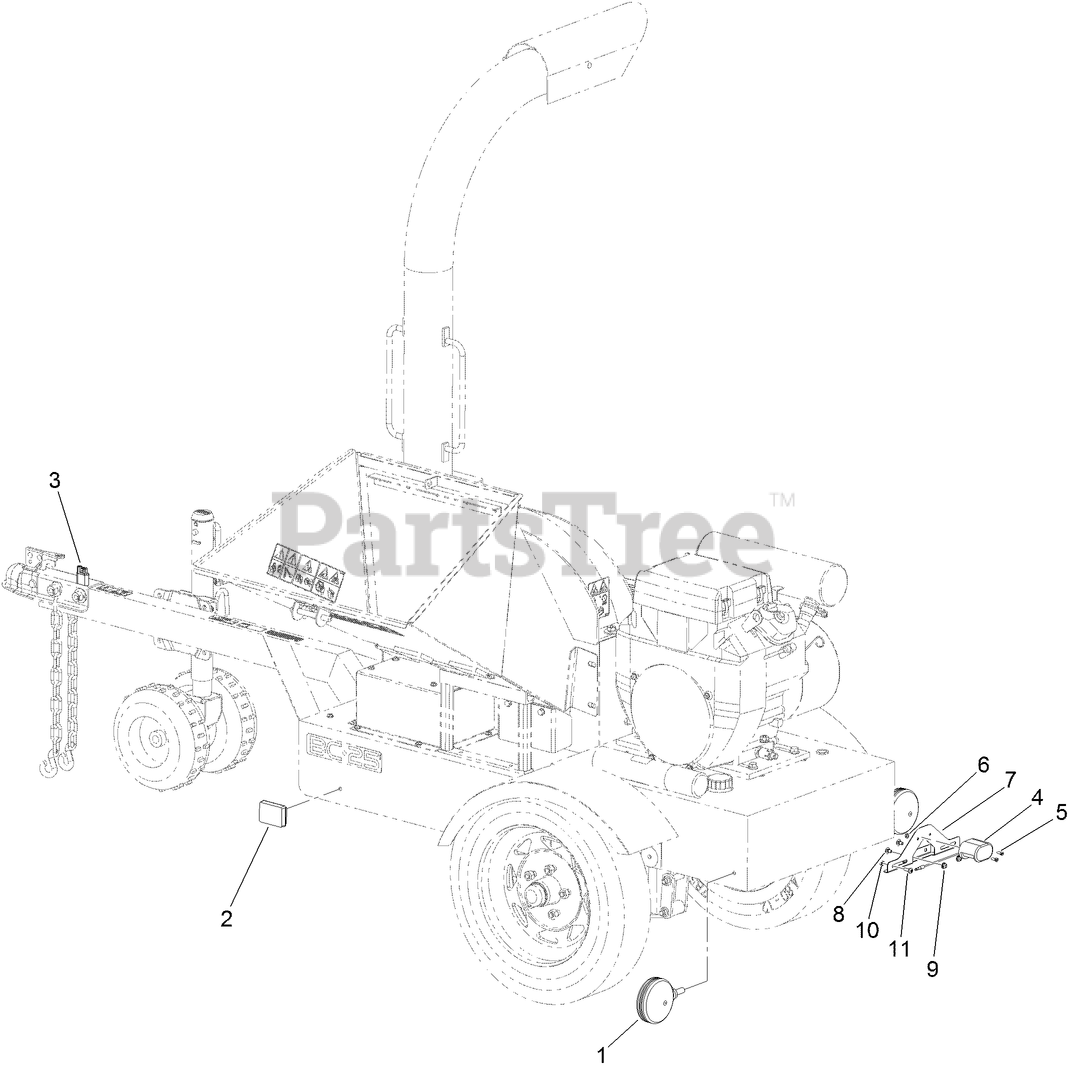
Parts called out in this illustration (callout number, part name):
1	LIGHT-TAIL
2	LIGHT-MARKER
3	HARNESS-TRAILER
4	LAMP-LICENSE
5	SCREW-SHH
6	NUT-LOCK, NI
7	BRACKET-PLATE, LICENSE
8	SCREW-CARR
9	NUT-HF
10	NUT-LOCK
11	SCREW-PPH
